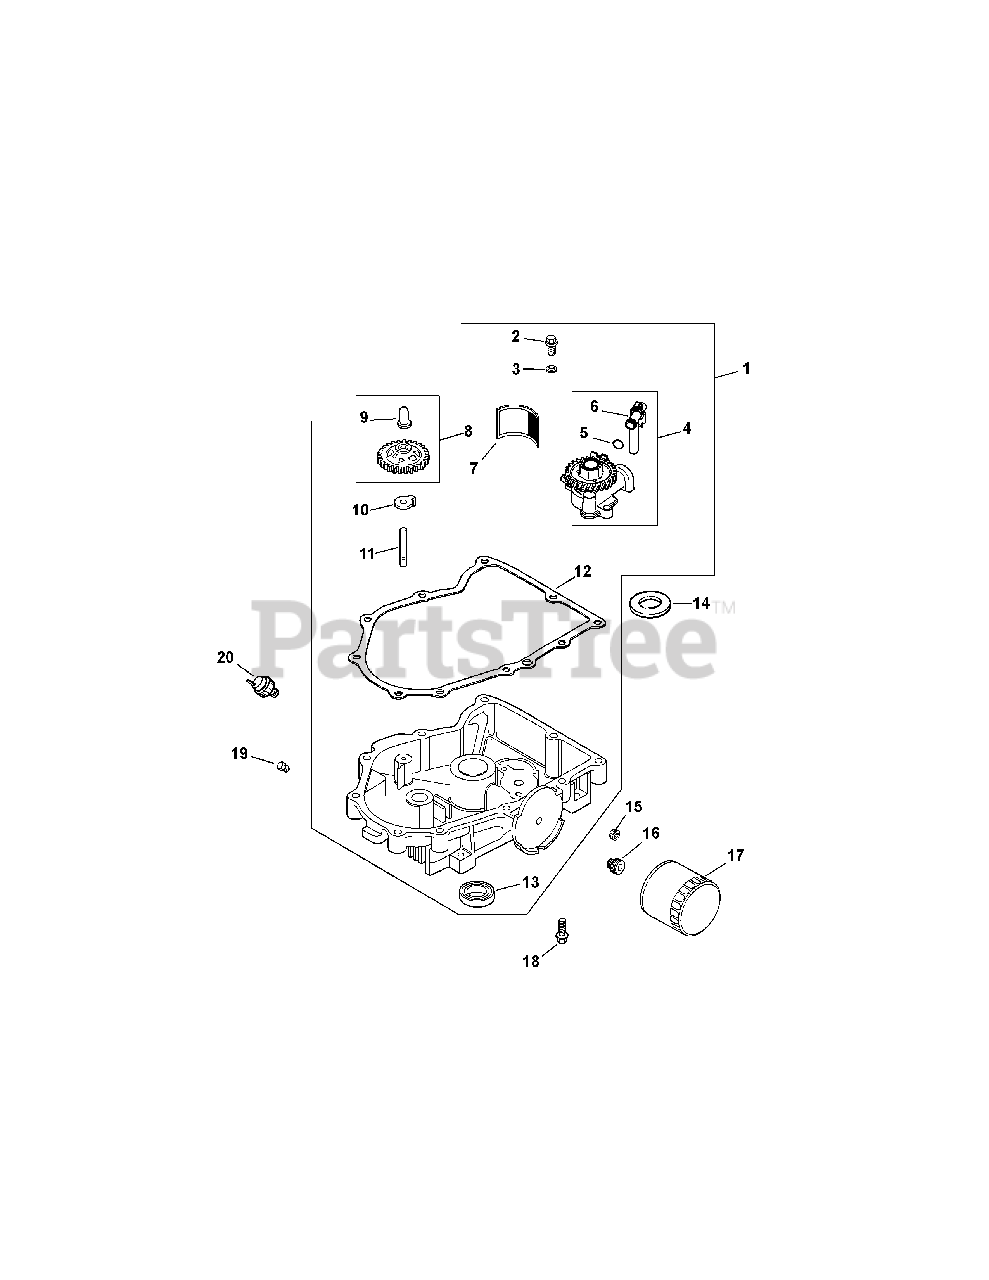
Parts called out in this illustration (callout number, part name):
1	KIT, OIL PAN ASSEMBLY (includes 2-13)
2	SCREW, FLG THD FRM M6X1.0X25
3	WASHER, FLAT 6 MM
4	KIT, OIL PUMP ASSEMBLY (includes 5,6)
5	O-RING, OIL PICK-UP
6	KIT, OIL PICK-UP TUBE
8	KIT, GOVERNOR GEAR W/PIN (includes 9)
9	PIN, GOVERNOR REGULATING
11	SHAFT, GOVERNOR GEAR
12	KIT,OIL PAN GSKT(SELECT-A-SEAL)
14	SHIM, THRUST (BLACK .686MM)
15	PLUG, PIPE CTSK 3/8''
16	NIPPLE, OIL FILTER
18	SCREW, FLG M8X1.25X45
20	PLUG, HD PIPE 3/8''
21	SWITCH, OIL PRESSURE
